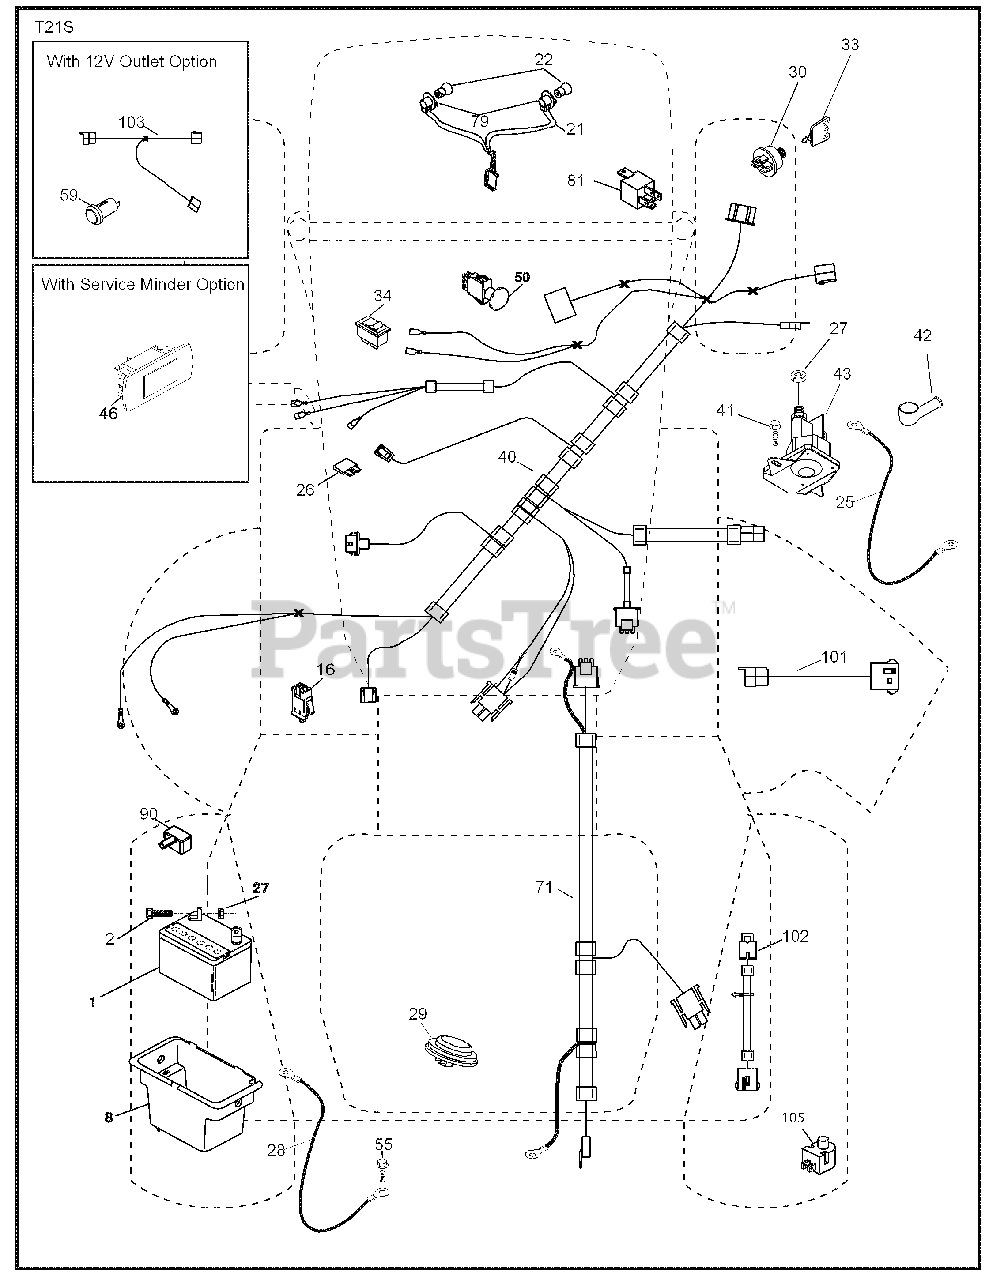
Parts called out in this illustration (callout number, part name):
1	Battery
2	Bolt Hex Head 1/4-20 x 3/4
8	Box Battery
16	Switch Interlock Push-In
21	Harness Socket Light w/4152J
22	Bulb Light
25	Cable Starter
27	Nut Keps Hex 1/4-20 unc
28	Cable, Ground
29	Switch, Seat
30	Switch, Ign
34	Switch Light/Reset
40	Harness Ign. Dash
41	Screw Thd Cut 1/4-20 x 1/2
42	Cover, Terminal
43	Solenoid
46	Gauge Service Reminder Hrmtr
50	Switch PTO
55	Screw Thdrol 5/16-18 x 3/4 TYTT
59	Outlet 12-Volt
71	Harness Ign.
79	Socket Asm Bulb Twistlock
90	Cover Terminal
101	Harness Pigtail
102	Harness Pigtail
103	Harness 12-Volt Pigtail
105	Switch Reverse TT Pedal Control
